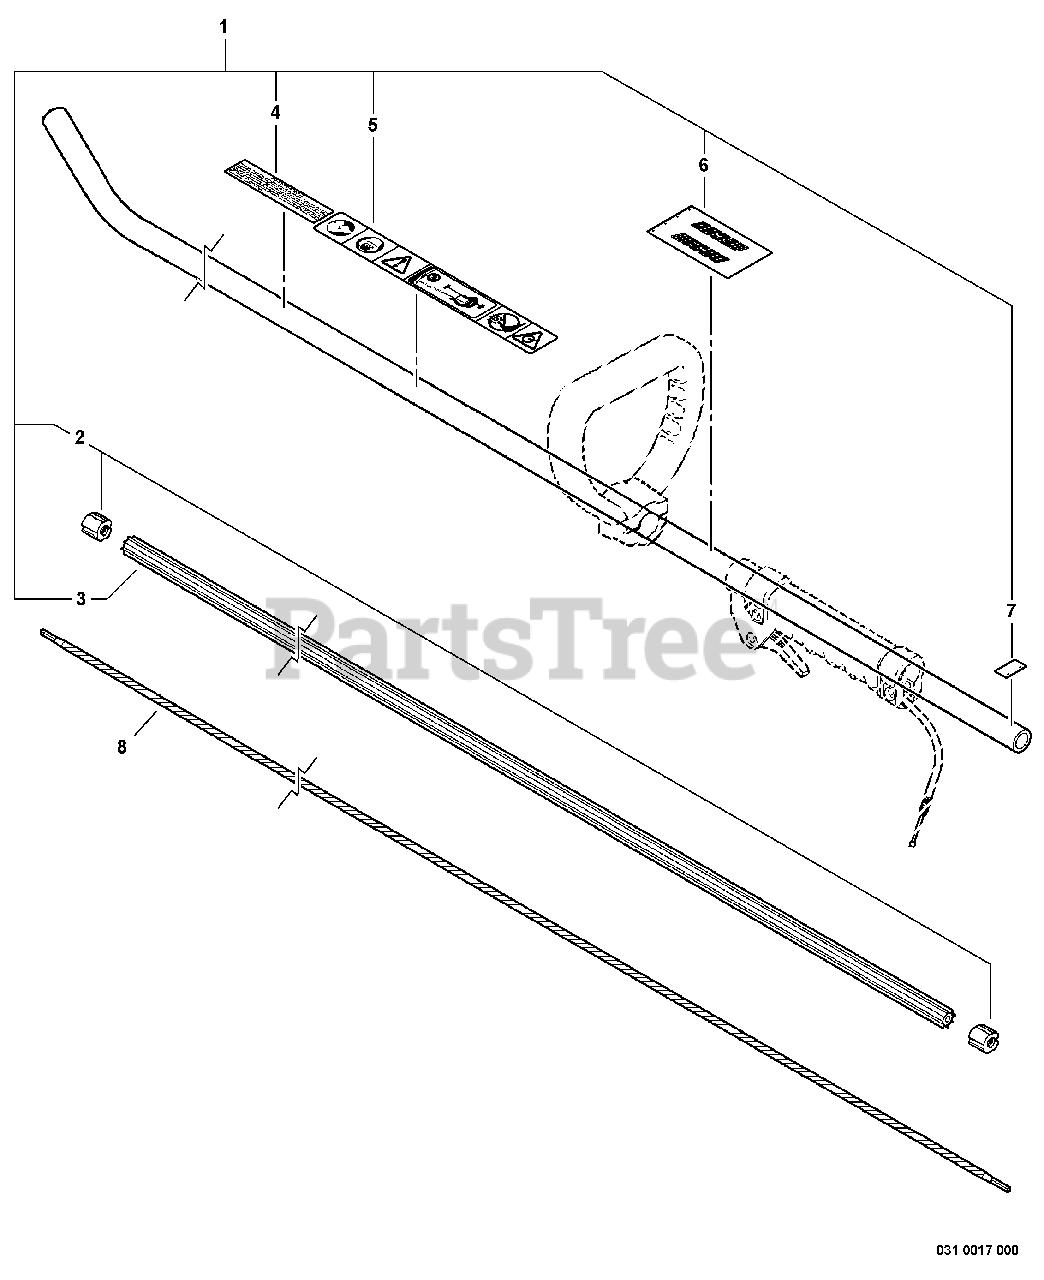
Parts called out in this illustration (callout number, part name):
1	MAIN PIPE ASSY
3	LINER - FLEXIBLE
4	LABEL, CAUTION
5	LABEL, CAUTION
6	LABEL, HANDLE LOCATION
7	LABEL - ALIGNMENT
8	DRIVESHAFT - FLEXIBLE L= 1522
